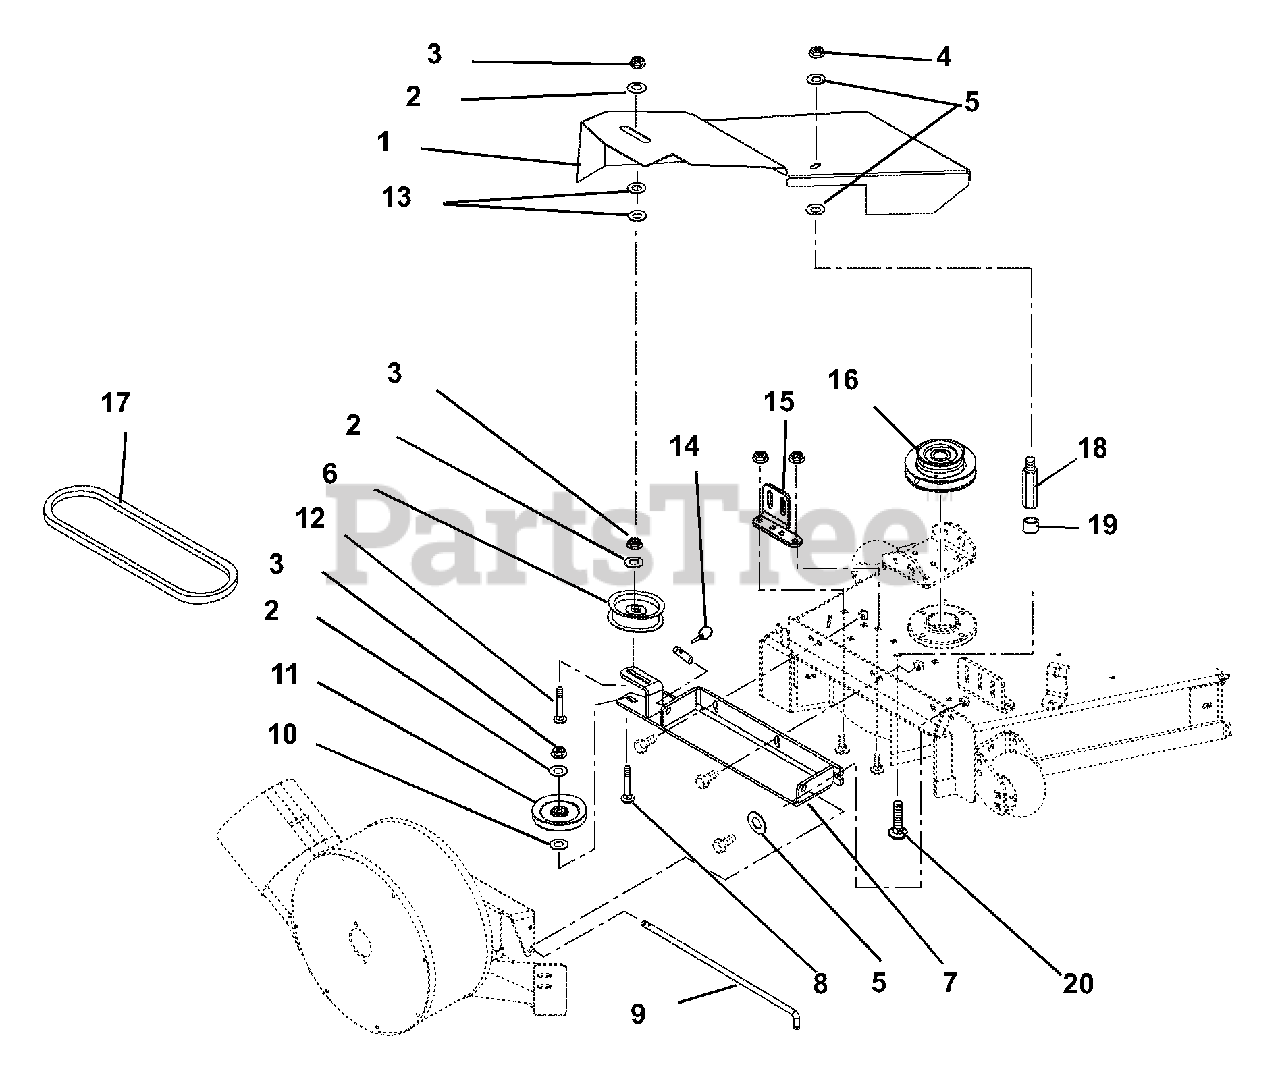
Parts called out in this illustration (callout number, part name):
1	Weldment, Belt Guard
2	Washer-Flat-Steel .438 x 1.00 x .083
3	Nut-Locking-Top-Flange .38-16
4	Nut-Locking-Top-Flange .31-18
5	Washer-Flat-Steel .38 x .875 x .083
6	Idler Flanged 3.50
7	Weldment, Pivot Mount 44,48,52
8	Bolt-Round Head Square Neck .38-16 x 1.75 Grade 5
9	Rod, Pivot
10	Washer-Flat-Steel .406 x 1.00 x .188
11	Idler-V 4.00 x .38
12	Bolt-Round Head Square Neck .38-16 x 2.50 Grade 5
13	Washer-Flat-Steel .406 x 1.375 x .135
14	Pin-Klik 1.00 x .188 x 1.25
15	Bracket, 44- & 48-Inch Mower Deck Mounting
15	Bracket, 52-Inch Deck Mounting
15	Bracket , 52-Inch Mower Deck Mounting
16	Pulley, Double V 3.50/5.25 Diameter
17	V-Belt, 44- & 48-Inch Mower Deck
17	V-Belt 52-Inch Mower Deck
18	Standoff, 2.75 x 5/16-18
19	Spacer, .380 x .503 x .281
20	Bolt, Round-Head-Square-Neck .31-18 x 1.00 Grade 5
